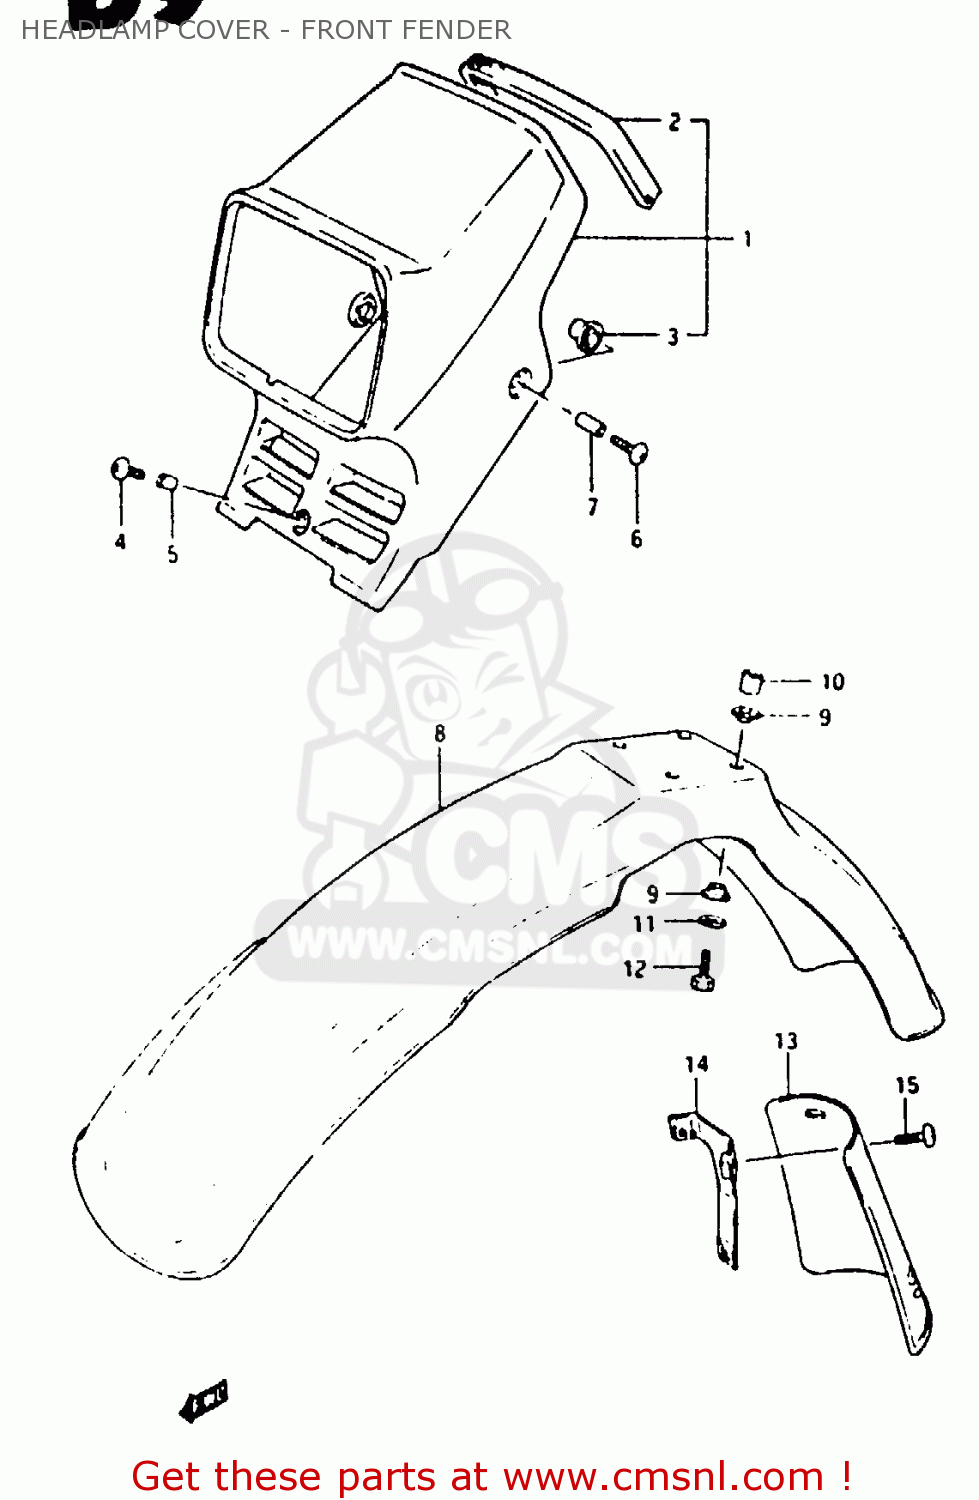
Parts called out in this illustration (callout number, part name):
1	COVER, HEADLAMP (RED/BLACK)
2	CUSHION,HEAD LAMP HOUSING
3	SPACER,HEAD LAMP COVER
4	SCREW
5	SPACER (6.1X8X12)
6	SCREW
7	SPACER (6.1X8X15.5)
8	FENDER,FRONT
9	SPACER
10	SPACER (6.8X10X10)
11	WASHER,LOCK
12	BOLT
